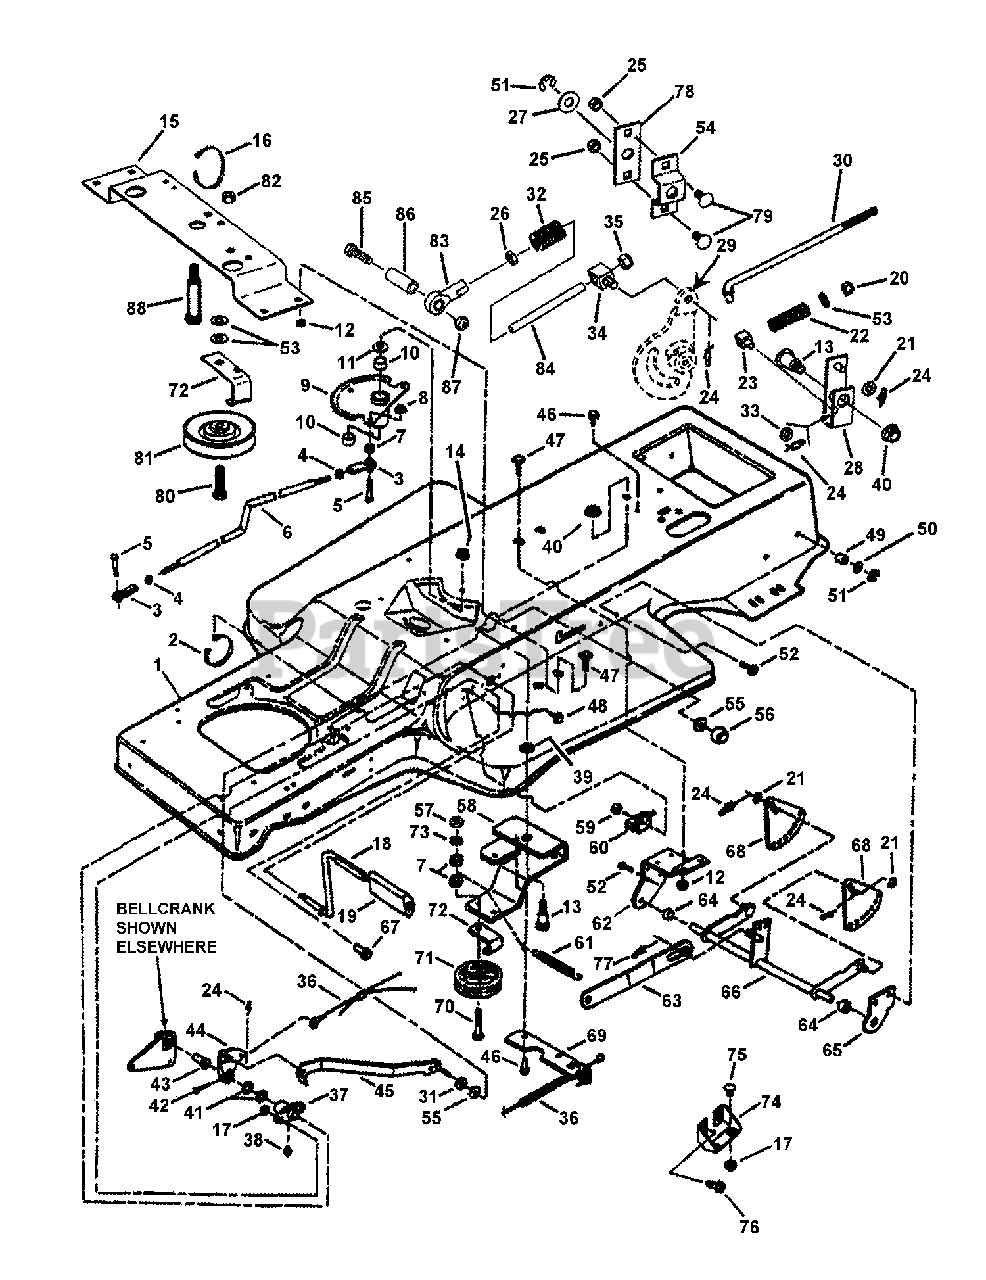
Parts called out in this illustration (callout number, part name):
1	FRAME, Tractor (I piece)
2	CABLE TIE, 3.19
3	ROD END, Pump Control Linkage, 3/8-24 thread
4	NUT, 3/8-24 Hex Jam
5	SCREW, 3/8-24 x 1-1/4" Square Neck Carriage
6	DRAGLINK
7	SPACER, Tie Rod
8	NUT, 3/8-16 Hex Flange Lock
9	ASSEMBLY, Steering Sector (Includes 41267, Weldment & item 10)
10	BEARING, Sleeve, .875 0.D. x .75
11	THRUST WASHER
12	NUT, 1/4-20 Hex Flange Lock
13	SHOULDER BOLT, 1/2-13 thread
14	NUT, 1/2-13 Hex Center Lock, GR A
15	BRACE, Sector Gear
16	CABLE TIE, 7"
17	NUT, 5/16-18 Hex Flange Lock, GR5
18	PEDAL, Clutch/Brake
19	PEDAL PAD
20	NUT, 3/8-16-3B Hex Nyloc
21	WASHER, 3/8" Flat SAE
22	SPRING, Brake
23	SWIVEL, Inline Brake Arm
24	COTTER PIN, 3/8 x 1-7/32" Self Lock
25	NUT, 5/16-18 Hex Center Lock, GR5 or B
26	NUT, 5/16-24 Hex Jam
27	WASHER, .44" I.D. Flat
28	WELDMENT, Brake Bellcrank
29	ARM, Speed Control (Component of Transaxle, see Transmission Page)
30	ROD, Brake- K46
31	WASHER, 5/16 x .11/16 x .08 Flat
32	SPRING, Rectangular Wire Die, Blue
33	WASHER, 13/32 x 3/4" Flat
34	SWIVEL, Shift Linkage- PM
35	NUT, 5/16-24 Hex Nyloc
36	CABLE, Clutch/Brake- K46
37	ASSEMBLY, Pivot-Foot Shaft (Includes item 38)
38	LUBE FITTING, Straight (press-fit for .187 dia. Hole)
39	WASHER, 1/2" Internal Tooth Lock
40	NUT, 1/2-13 Hex Flange Lock
41	WASHER, .64 x .99 x .05 Flat
42	PIN, 3/16 x 1-1/2" Clevis
43	BEARING, Flange
44	ASSEMBLY, Clutch/Brake Arm
45	WELDMENT, Parking Brake, OPPLT
46	SCREW, 5/16-18 x 5/8" Hex Washer Self-Tap
47	BOLT, 1/4-20 x 5/8" Flat Head Square Neck, GR2
48	SCREW, #10-32 x 5/8" Hex Washer Head Machine, GR5
49	BUSHING, 1/2" Nylon
50	WASHER, .531 x 1.062 x .121 Flat SAE
51	RING, 1/2" External Retaining
52	SCREW, 5/16-18 x 5/8" Truss Head (Torx)
53	WASHER, 3/8" Flat
54	BRACKET, Pivot Mounting
55	WASHER, 5/16 Nylon
56	KNOB, Brake/Clutch- 5/16-18 thread
57	NUT, 3/8-16 Hex , GR5 or B
58	ARM, Idler-Traction Drive
59	NUT, #10-32 Hex Nyloc
60	SWITCH- DPDT NC/NO
61	SPRING, Traction Drive
62	BRACKET, Rear Lift/PTO Lever, Extruded
63	LINK, Lift (33" Deck)
63	LINK, Lift (38" Deck)
64	SPACER, .515 x .688 x .403
65	BRACKET, Deck Hang Pivot
66	WELDMENT, Rear Lift Arm, 33" Deck
66	WELDMENT, Rear Lift, 38" Deck
67	SCREW, 5/16-18 x 7/8" Truss Head (Torx)
68	SECTOR, Lift Plate
69	EXTENSION, Idler Arm
70	SCREW, 3/8-16 x 2-1/2" Hex Head Cap, GR5
71	PULLEY, 3.47 O.D. Flat Idler
72	BELT GUIDE, 3-1/2" Dia.
73	WASHER,3/8" Split Lock
74	BRACKET, Frame Brace
75	BOLT, 5/16-18 x 1/2" Short Neck Carriage, GR5
76	SCREW, 5/16-18 x 3/4" Hex Washer Self-Tap
77	PIN, 3/8 Self Lock Cotter
78	BRACKET, Mounting Brace
79	BOLT, 5/16-18 x 3/4" Square Neck Carriage GR5
80	SCREW, 3/8-16 x 1-1/2" Hex Head Cap, GR5
81	PULLEY, Idler V, 3.30 HA
82	NUT, 3/8-16 Hex Center Lock, GR5 or B
83	ROD END, Pump Control Linkage, 5/16-24 thread
84	ROD, Shift Linkage
85	SCREW, 5/16-18 x 1-1/2" Hex Head Cap, GR5
86	SPACER, .38 I.D. x .56 O.D. x .75 thick
87	NUT, 5/16-18 Hex Center Lock, GR5 or B
88	SHOULDER BOLT, 1/2-13 thread x 3"
